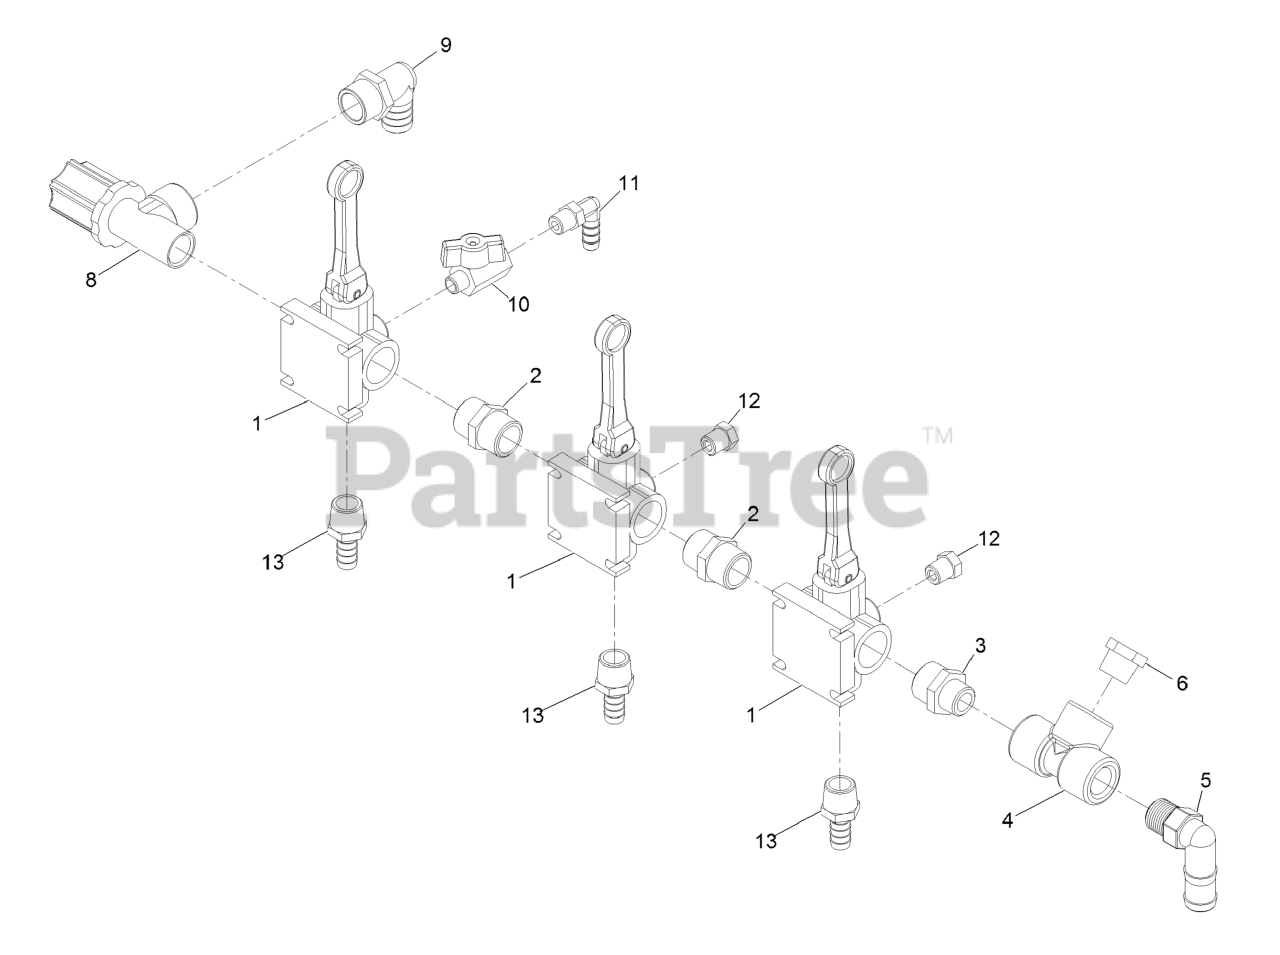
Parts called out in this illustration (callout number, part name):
1	VALVE-DIRECTO
2	FITTING-NIPPLE
3	FITTING-NIPPLE
5	ELBOW-90
6	FITTING-REDUCER
8	VALVE-THROTTLE
9	FITTING-ELBOW, 90
10	VALVE-CHROME, 1/4
11	FITTING-ELBOW, 90
12	PLUG-VALVE
13	FITTING-HOSEBARB
